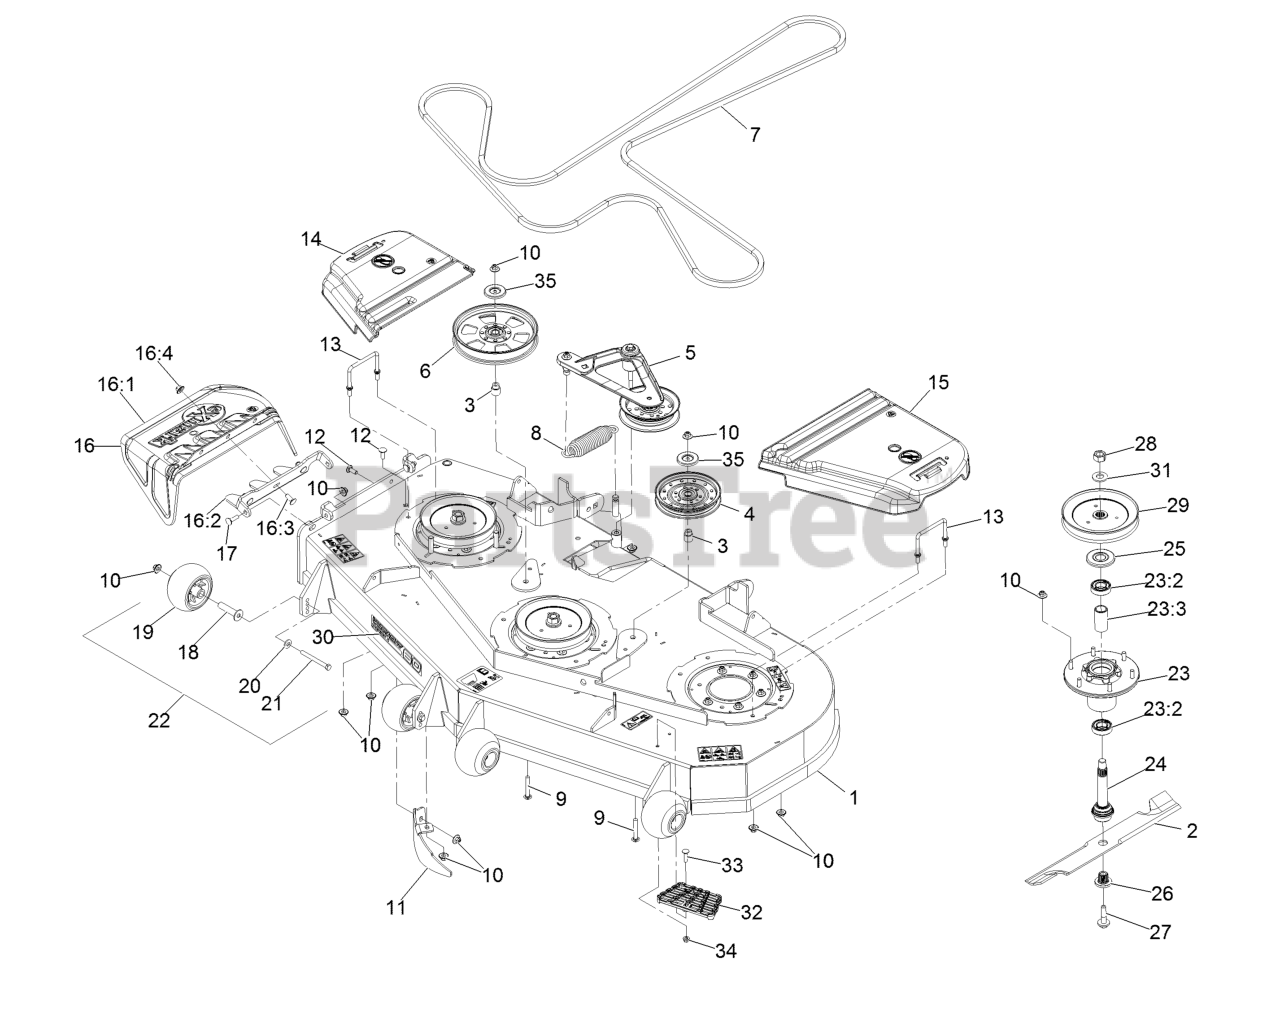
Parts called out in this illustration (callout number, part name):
1	Deck ASM,W/Decals 60
2	Blade, Solid
2	Blade, Low Lift
2	Blade, Mulching
2	Blade, Notched
2	Blade-Extreme 2, 20.50"
3	Bushing, Idler
4	Idler-Pulley
5	Deck Idler ASM
6	Pulley-Idler, Flat
7	Belt,V-5V-198.75
8	Spring-Extension
9	Bolt-Carriage 3/8-16 X 2 1/2
10	Nut-Nyloc 3/8-16 Flg
11	Dogleg - Lz60
12	Bolt-Carriage 3/8-16 X 1
13	Wireform-Cover
14	Cover-Belt, RH
15	Cover-Belt, LH
16	ASM,Discharge Chute
16:1	Chute, Discharge
16:2	Bracket,Discharge Chute
16:3	Bolt-Carriage 3/8-16 X 1
16:4	Nut-Nyloc 3/8-16 Flg
17	Bolt-Carriage 3/8-16 X 1 1/4
18	Axle, Roller
19	Roller-Anti-Scalp
20	Washer-Spring Disc 3/8
21	Screw-HH 3/8-16 X 3 3/4 GR 8
22	Kit, Anti-Scalp Roller
23	ASM-Cutter Hsg With Bearings
23:2	Bearing-Ball
23:3	Spacer-Bearing
24	Sub-Contract Bom
24	ASM-Spindle And Seal
25	Guard,Bearing Top .989
26	Bushing, Splined
27	Screw-Sems 1/2-20 X 2.19
28	Nut-Hex
29	Sheave,Blade Drive 7.25
30	Decal, 604
31	Washer-Spring Disc 3/4
32	Step-Deck
33	Bolt-Carriage 5/16-18 X 1 1/4
34	Nut-Nyloc 5/16-18 Flg
35	Shield-Dust
